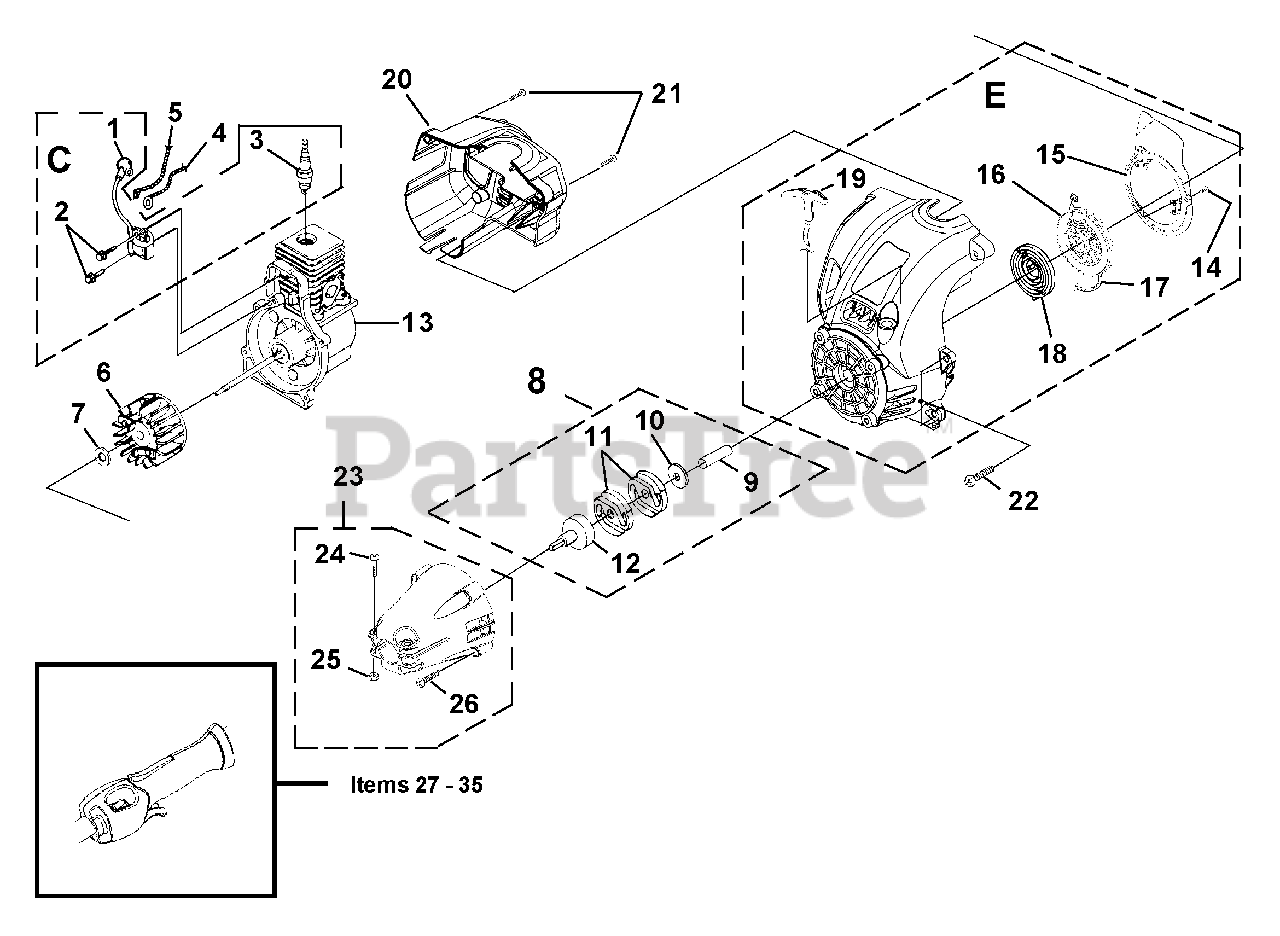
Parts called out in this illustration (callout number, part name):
1	IGNITION MODULE
2	SCREW-Taptite (8-32 X 1")
3	SPARK PLUG
4	LEAD-Electrical
5	LEAD-Electrical
6	ROTOR KIT
7	WASHER-Flat
8	CLUTCH AND DRUM KIT
9	SPACER
10	WASHER-Flat
12	CONNECTOR AND DRUM
13	SHORT BLOCK (See Engine Internal)
14	SCREW-Thread Form (8-16 X 1/2")
15	BAFFLE-Air
16	PULLEY-Starter
17	ROPE-Starter (42")
18	SPRING & CONTAINER
19	GRIP-Starter
20	HOUSING-Rear Kit
21	SCREW-Plastite (10-14 X 7/8")
22	SCREW-Taptite (10-24 X 3/4")
23	ADAPTOR
24	SCREW-Torx Hd. (10-24 x 1.25")
25	NUT-Flange
26	SCREW-Torx Hd. (10-14 x 3/4")
27	CONTROL HANDLE ASSY.
28	TRIGGER-Throttle
29	SPRING-Extension
30	WASHER-Lock (#6)
31	THROTTLE LOCKOUT
32	CABLE ARM
33	SCREW-Thread Form (8-16 x 3/4")
34	CABLE-Throttle
35	LEAD-Electrical
C	IGNITION KIT
E	COMPLETE STARTER ASSEMBLY
